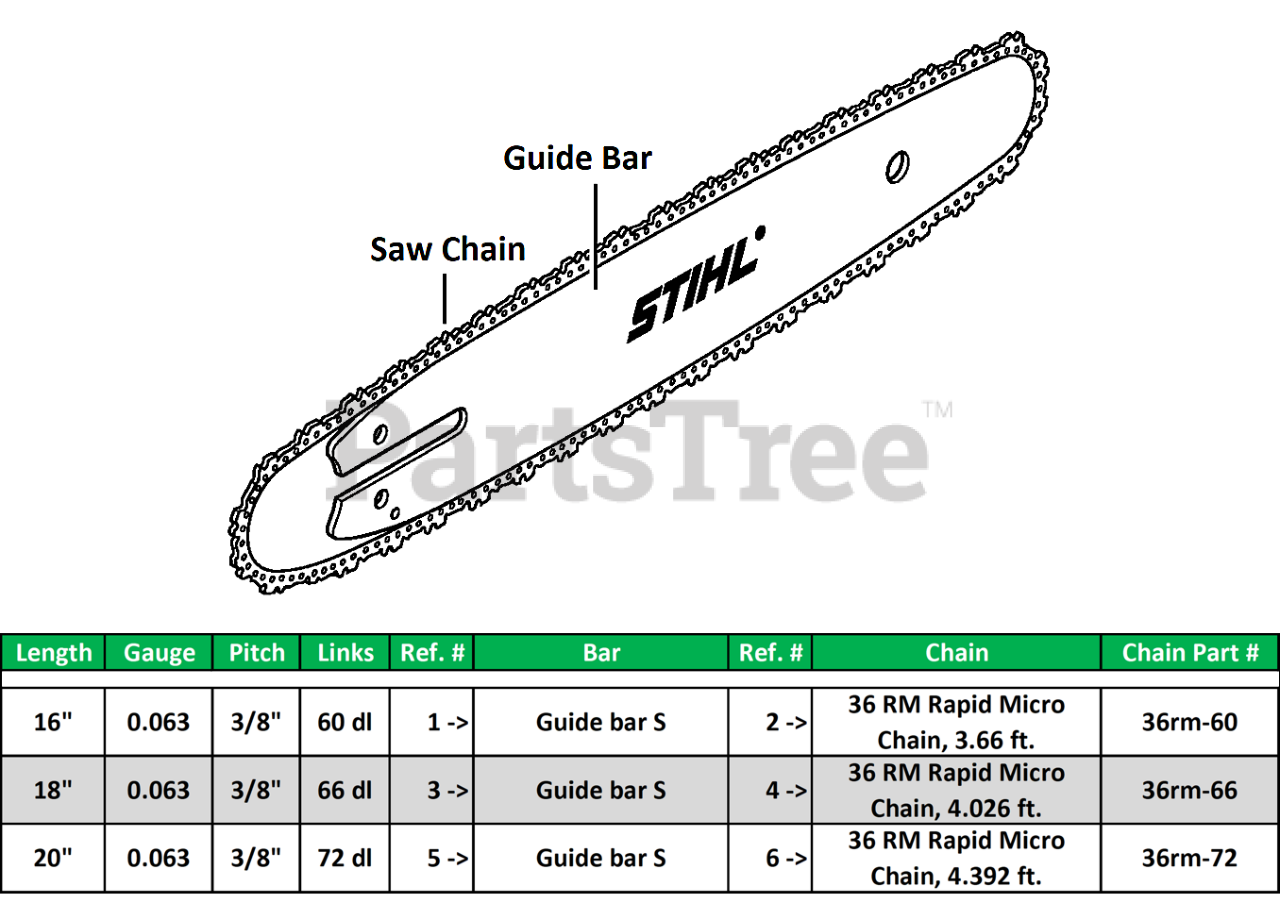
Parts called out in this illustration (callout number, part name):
1	Guide bar S 40cm/16" 1,6mm/0.063" 3/8"
2	36 RM Rapid Micro Chain, 3.66 ft.
3	Guide bar S 45cm/18" 1,6mm/0.063" 3/8"
4	36 RM Rapid Micro Chain, 4.026 ft.
5	Guide bar S 50cm/20" 1,6mm/0.063" 3/8"
6	36 RM Rapid Micro Chain, 4.392 ft.
